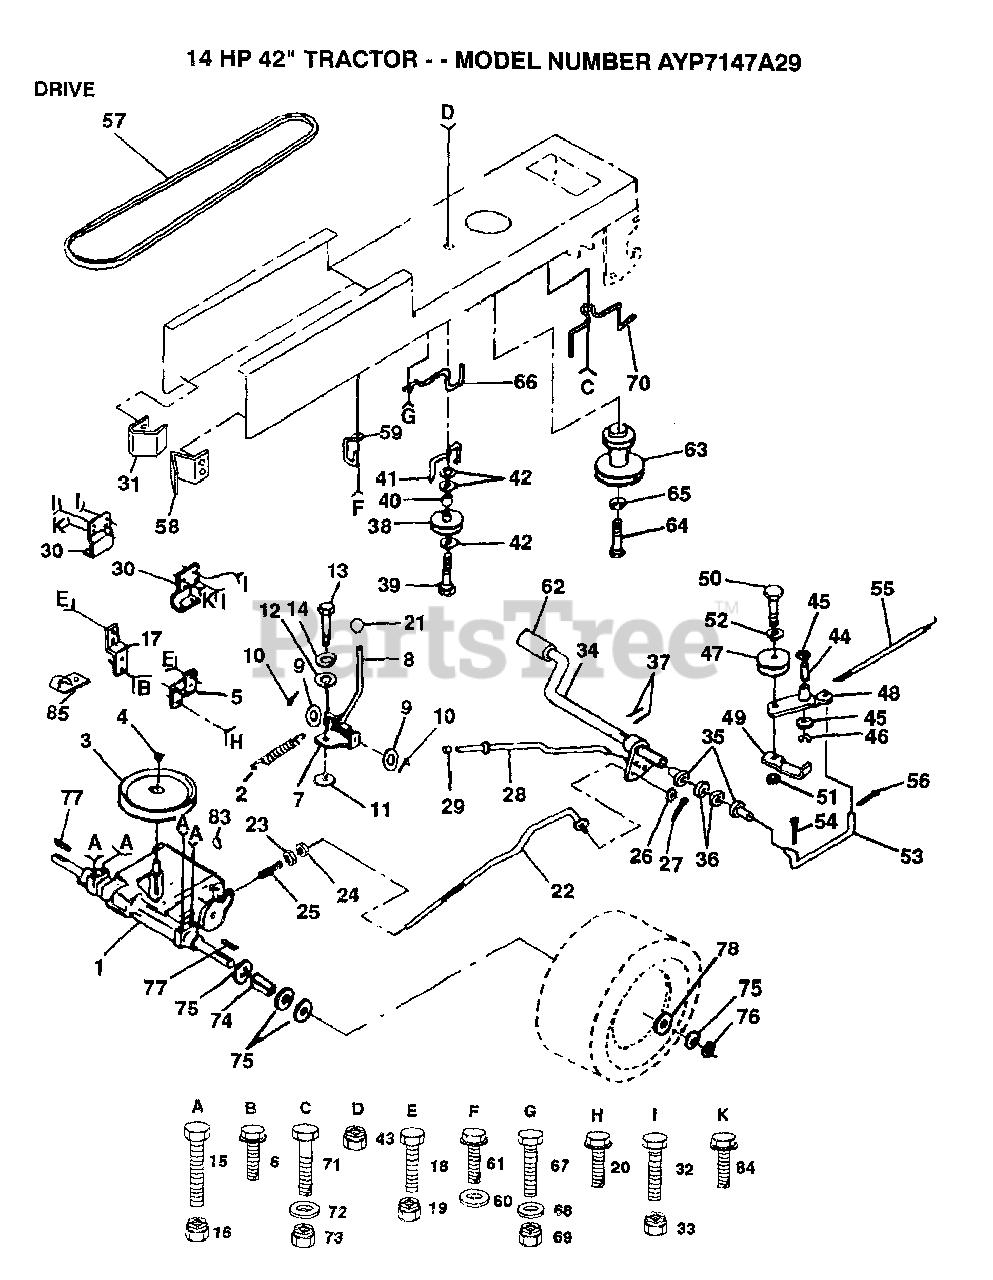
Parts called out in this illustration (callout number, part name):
3	PULLEY TRANS
5	STRAP TORQUE
6	SCREW
8	SHIFT ROD
9	WASHER
10	PIN COTTER 1/8
11	WASH-SHFT PLT LT
12	WASHER LT
14	LOCKWASHER
15	BOLT
17	STRAP TORQUE
20	SCREW
21	KNOB T (1/2-HOLE)
22	BRAKE ROD
23	NUT
24	NUT
25	SPRING ROD LT
26	WASHER
27	COTTER PIN
28	BRAKE PARK ROD
29	PLUNGER CAP T
30	TRANSAXLE MTG BKT
31	"KEEPER,BELT LH T"
32	BOLT
35	NYLON BEARING
36	WASHER LT
38	PULLEY.IDLER.FLAT
39	BOLT
40	SPACER T
41	BELT KEEPER LT
42	WASHER
44	"LY, BEARING"
45	WASHER LT
46	KLIP RING
48	ARM IDLER
49	RETAIN BELT
52	WASHER
53	"LINK, CLUTCH T"
54	COTTER PIN
55	"SPRING, RETURN LT"
56	COTTER PIN
58	"KEEPER,BELT RH T"
60	WASHER
61	SCREW
62	PEDAL COVER T
64	BOLT
65	LOCKWASHER
66	KEEPER.BELT.ENG.L
67	BOLT
68	WASHER
70	GUIDE BLT DR MWR
71	BOLT
72	WASHER
74	SPACER LT
75	WASHER
76	E-RING LT
77	SQUARE KEY
78	WASHER
84	SCREW
85	CLIP T
